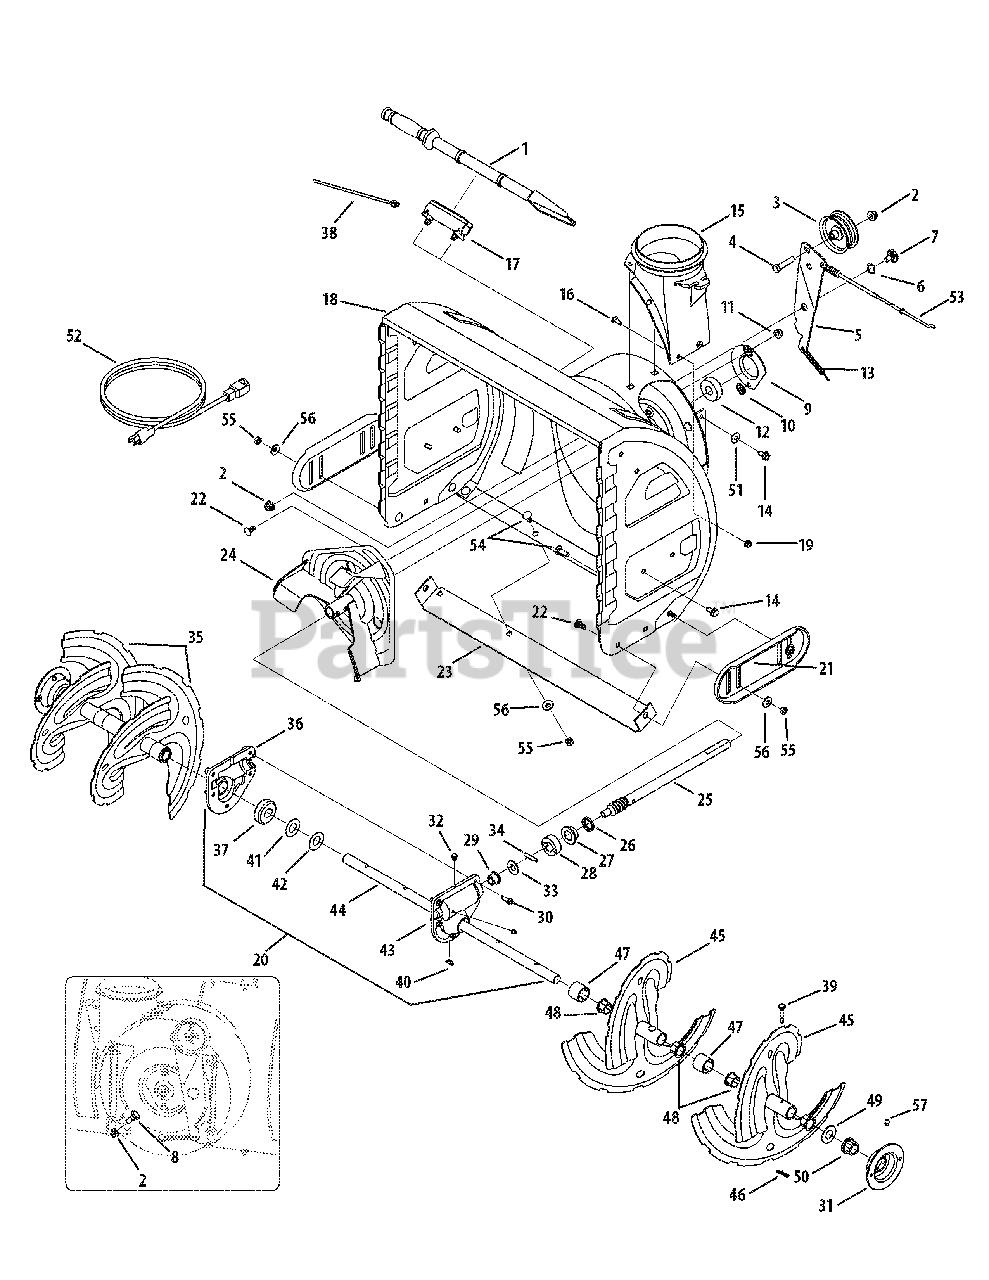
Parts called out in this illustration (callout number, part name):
1	Clean-Out Tool
2	Flange Lock Nut
3	Flat Idler Pulley
4	Hex Bolt, 3/8-16 x 1.75
5	Auger Idler Bracket
6	Wave Washer
7	Shoulder Screw
8	Shoulder Screw
9	Bearing Housing
10	Push Nut
11	Flange Lock Nut, 5/16-18
12	Ball Bearing
13	Extension Spring
15	Chute Adapter
16	Carriage Screw, 1/4-20 x 0.75
17	Clean-out Tool Mtg. Bracket
18	Housing Assembly, Auger, 28"
19	Flange Lock Nut, 1/4-20
20	Gearbox Assembly, Auger, 28"
21	Skid Shoe, Stainless
22	Carriage Bolt
23	Shave Plate, 28"
24	Impeller Assembly
25	Worm Shaft
27	Flange Bearing
28	Thrust Collar
29	Flange Bearing
30	TT Screw, 1/4-20 x 0.75
31	Bearing Housing
33	Flat Washer
35	Spiral Assembly - RH
36	Reducer Hsg. - RH
37	Worm Gear, 20T
38	Cable Tie
40	Hi-Pro Key
41	Flat Washer
42	Spacer, 1.25 x .75 x 3/16
43	Reducer Hsg. - LH
44	Axle, Auger, 28"
45	Spiral Assembly - LH
46	Bow Tie Cotter Pin
48	Flange Bushing
49	Flat Washer
50	Hex Flange Bearing
51	Bell Washer
52	Extension Cord. 3-Prong
53	Auger Clutch Cable
54	Carriage Bolt, 5/16-18 x .750
55	Hex Nut, 5/16-18
56	Bell Washer, .340 x .872 x .060
57	Drive Lube Fitting
